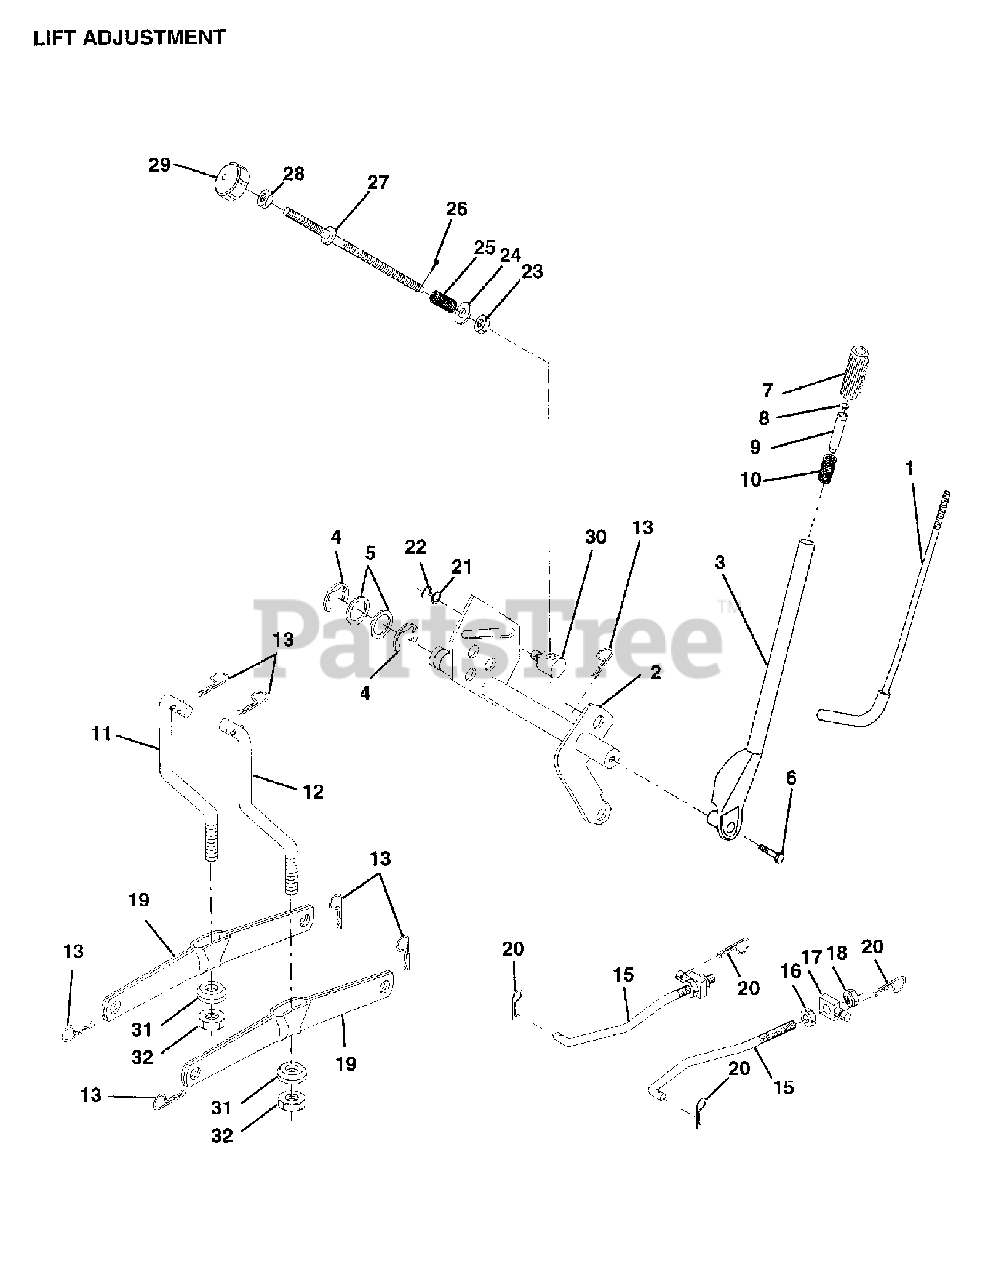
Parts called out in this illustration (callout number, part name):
1	LEVER ROD LT
3	LIFT LEVER KIT
6	Hex Bolt
7	GRIP
8	PLUNGER BUT KIT
9	PLUNGER BUT KIT
13	RETAINER SPRING
15	FRONT LINK
16	NUT.HEX.JAM.1/2-13
18	NUT.LK.W/WSH.1/2.
19	ARM.REAR.SUSPENSION
20	SPRING RETAINER
21	WASHER
22	KLIP RING
24	WASHER
27	ROD LIFT LT
28	NUT
29	KNOB INF 3/8-16
30	TRUNION LT
32	LOCK NUT
